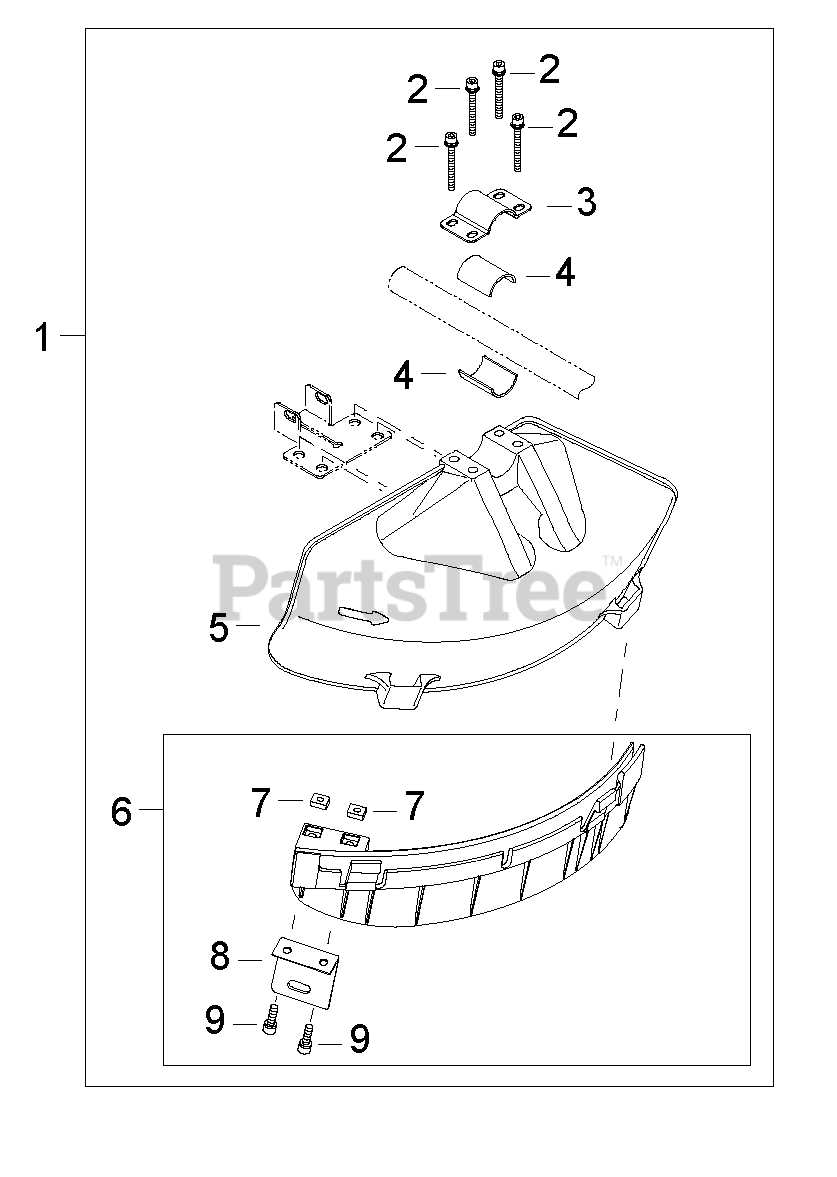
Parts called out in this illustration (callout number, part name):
1	DEBRIS SHIELD KIT
2	SCREW - 5X45
3	CLAMP - UPPER
4	SPACER
5	SHIELD, DEBRIS
6	SHIELD GUARD KIT
7	NUT - 5
8	KNIFE, TRIMMER LINE
9	SCREW - 5X16
